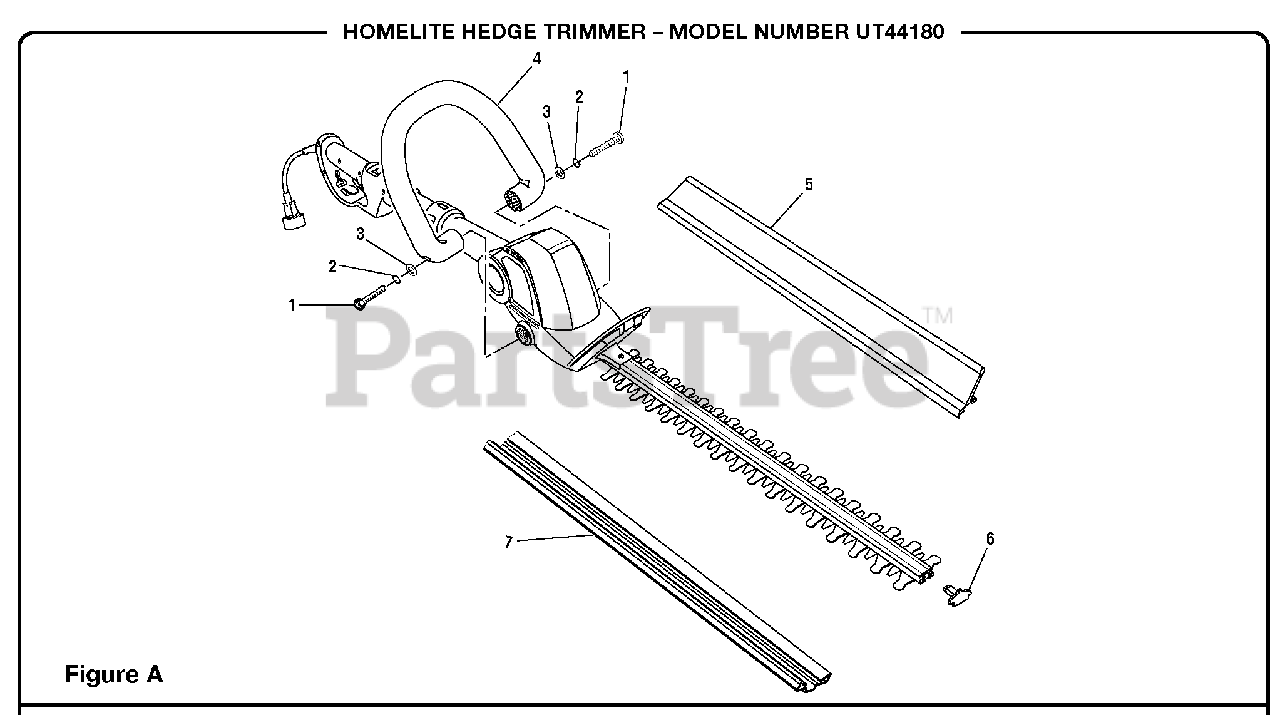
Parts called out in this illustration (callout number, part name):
1	Screw (M4 x 23)
2	Lock Washer
4	Front Handle
5	Debris Deflector
6	Deflector Retainer
